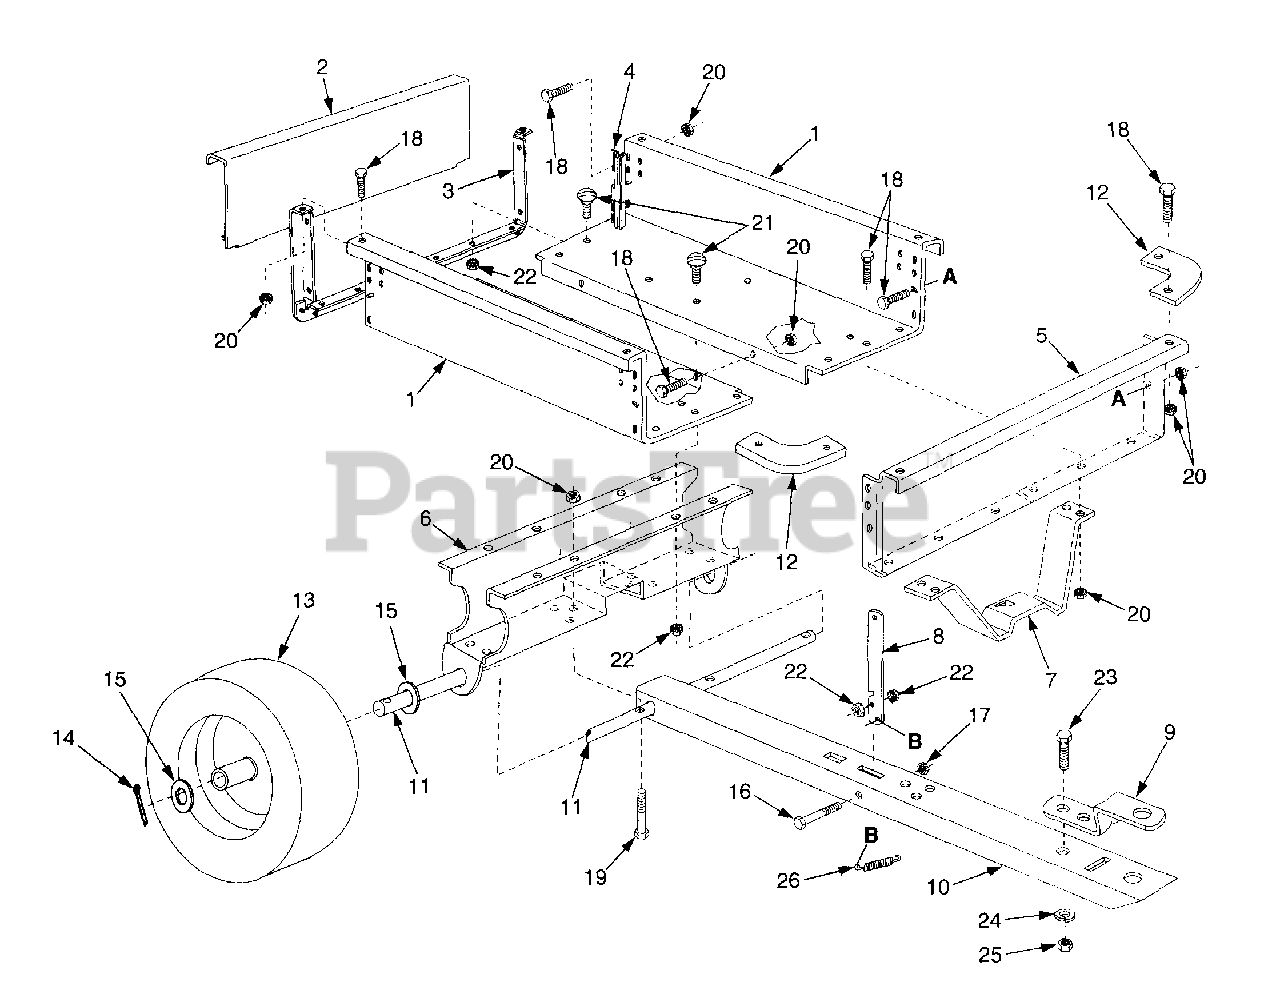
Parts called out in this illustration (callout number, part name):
8	Latch Lock Lever
14	Cotter Pin, 1/8" Dia. x 1"
15	Washer, Flat 3/4"
16	Hex Bolt, 5/16-18 x 3-3/4"
17	Hex Lock Nut, 5/16-18 Thread
18	Hex Bolt, 1/4-20 x 1/2"
19	Hex Bolt, 1/4-20 x 1-1/2"
20	Hex Nut, 1/4-20 Thread (Sems)
21	Slt. Truss Hd. Bolt 5/16-18 x 3/4" Lg.
22	Hex Nut, 5/16-18 Thread (Sems)
23	Hex Bolt, 3/8-16 x 1" Lg.
24	Lock Washer, 3/8"
25	Hex nut, 3/8-16 Thread
26	Extension Spring
